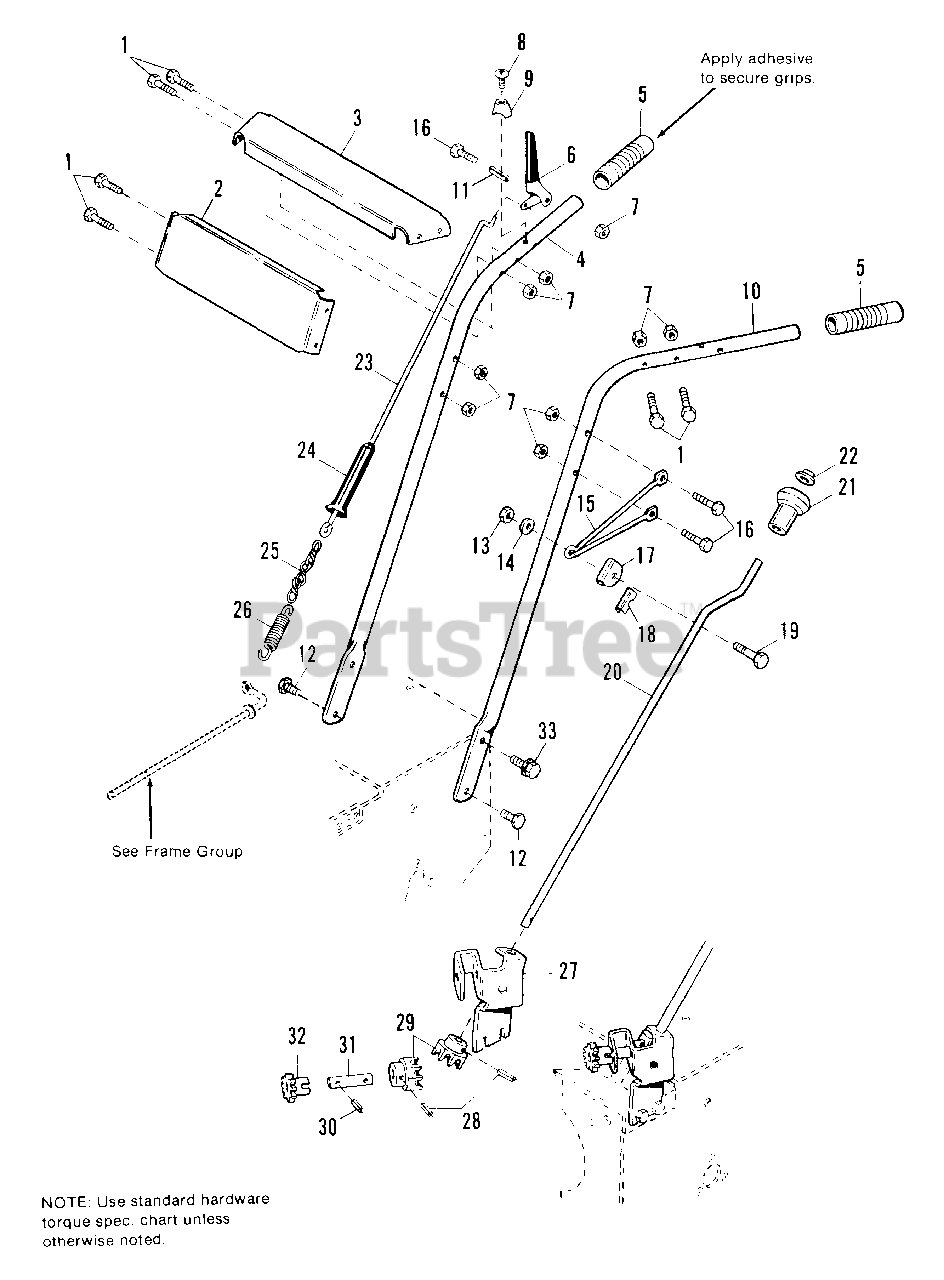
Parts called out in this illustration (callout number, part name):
1	CAPSCREW, Hex, 1/4-20 x 1-1/4
2	HANDLE PANEL, Lower
3	HANDLE PANEL, Upper
4	HANDLE, Tube, R.H.
5	GRIP, Handle
6	CLUTCH LEVER ASSY., R.H.
7	NUT, Centerlock, 1/4-20
8	SCREW, Thd. Cutting Pan Hd. #10-24
9	BUMPER, Clutch Lever
10	HANDLE, Tube, L.H.
11	SPACER, Clutch Lever
12	SCREW, Hex Flange Whizlock, 5/16-18 x 3/4
13	NUT, Hex, Centerlock, 5/16-18
14	WASHER, 5/16
15	BRACKET, Control Rod
16	CAPSCREW, Hex, 1/4-20 x 1-1/2
17	GUIDE, Adj. Rod
18	LINER, Adj. Rod Guide
19	CAPSCREW, Hex, 5/16-18 x 1-1/2
20	ROD, Chute Control
21	KNOB, Spout Rotator
22	PALNUT
23	ROD, Clutch
24	SLEEVE, Vinyl, Clutch Rod
25	CHAIN, Clutch Rod
26	SPRING, Clutch Rod
27	SUPPORT, Gear, Spout Rotator
28	PIN, Roll, 1/8 x 3/4
29	GEAR, Universal
30	PIN, Spring, 5/32 x 1
31	ROD, Chute, Lower
32	SPROCKET, Chute
33	SCREW, Hex Flange Whizlock, 5/16-18 x 1-1/4
